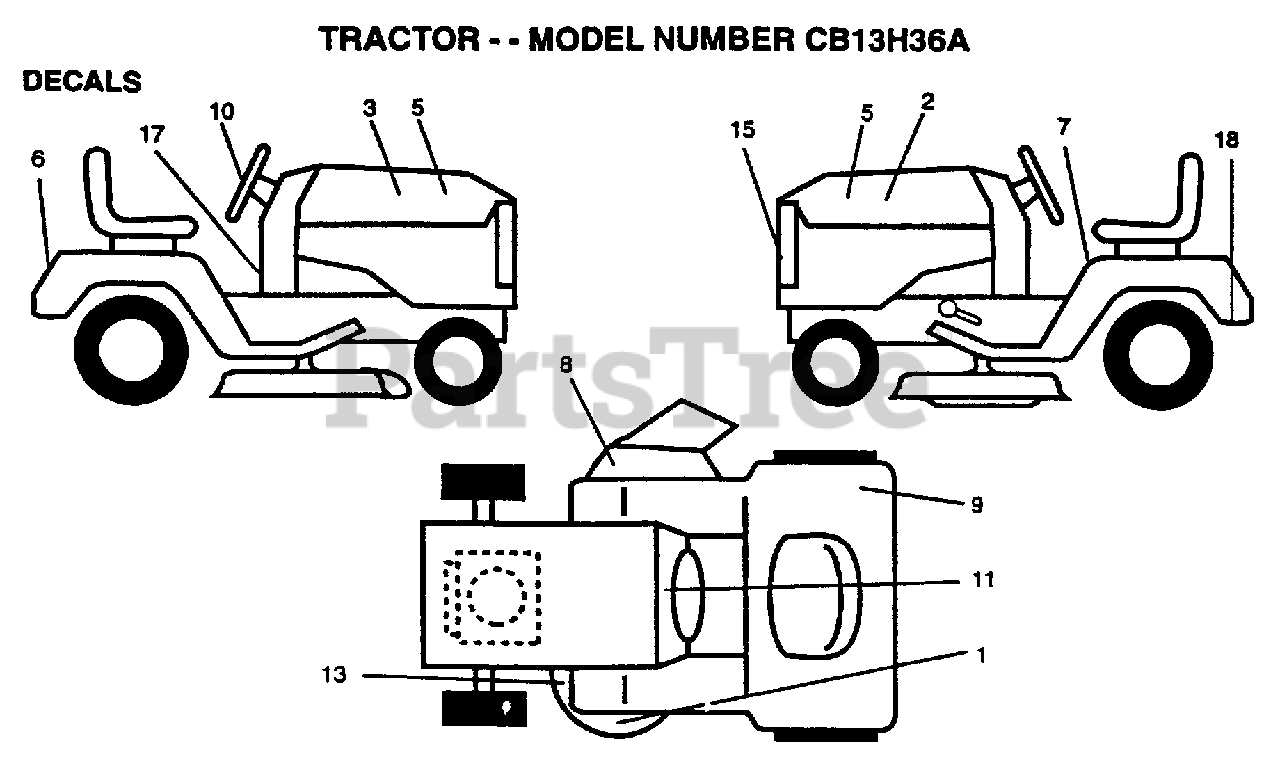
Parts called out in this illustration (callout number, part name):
2	DECAL.HOOD.LH.COO
3	DECAL.HOOD.RH.COO
5	DECAL.PNL.13H92
6	DECAL.FEND.COOPER
7	DECAL.READ.O.MANU
8	DECAL.DANGER.CUTF
10	DECAL.INS.WHL.STG
11	DECAL.OP.INST.SYM
13	DECAL.V.BELT
15	DECAL.GRILLE.COOP
17	DECAL.EURO.ST.CE.
18	DECAL.DRAWBAR.CTL
